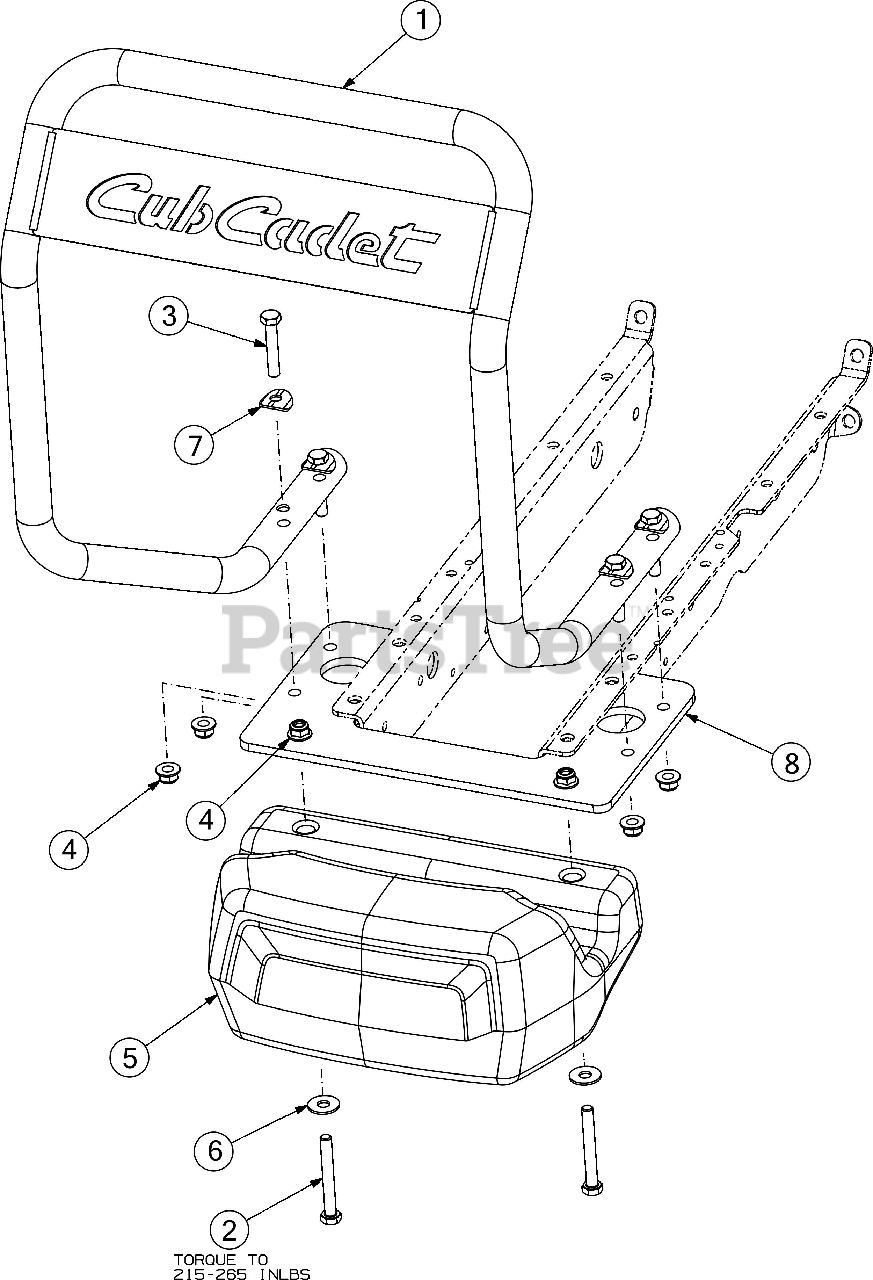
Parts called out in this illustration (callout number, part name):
1	FRONT BUMPER ASSEMBLY
2	SCREW 5/16-18 x 2.5 GR 5
3	SCREW 5/16-18 x 1.75 GR5
4	FLANGE LOCK NUT 5/16-18
5	COUNTERWEIGHT
6	FLAT WASHER
7	SADDLE WASHER
8	BUMPER MOUNTING PLATE
